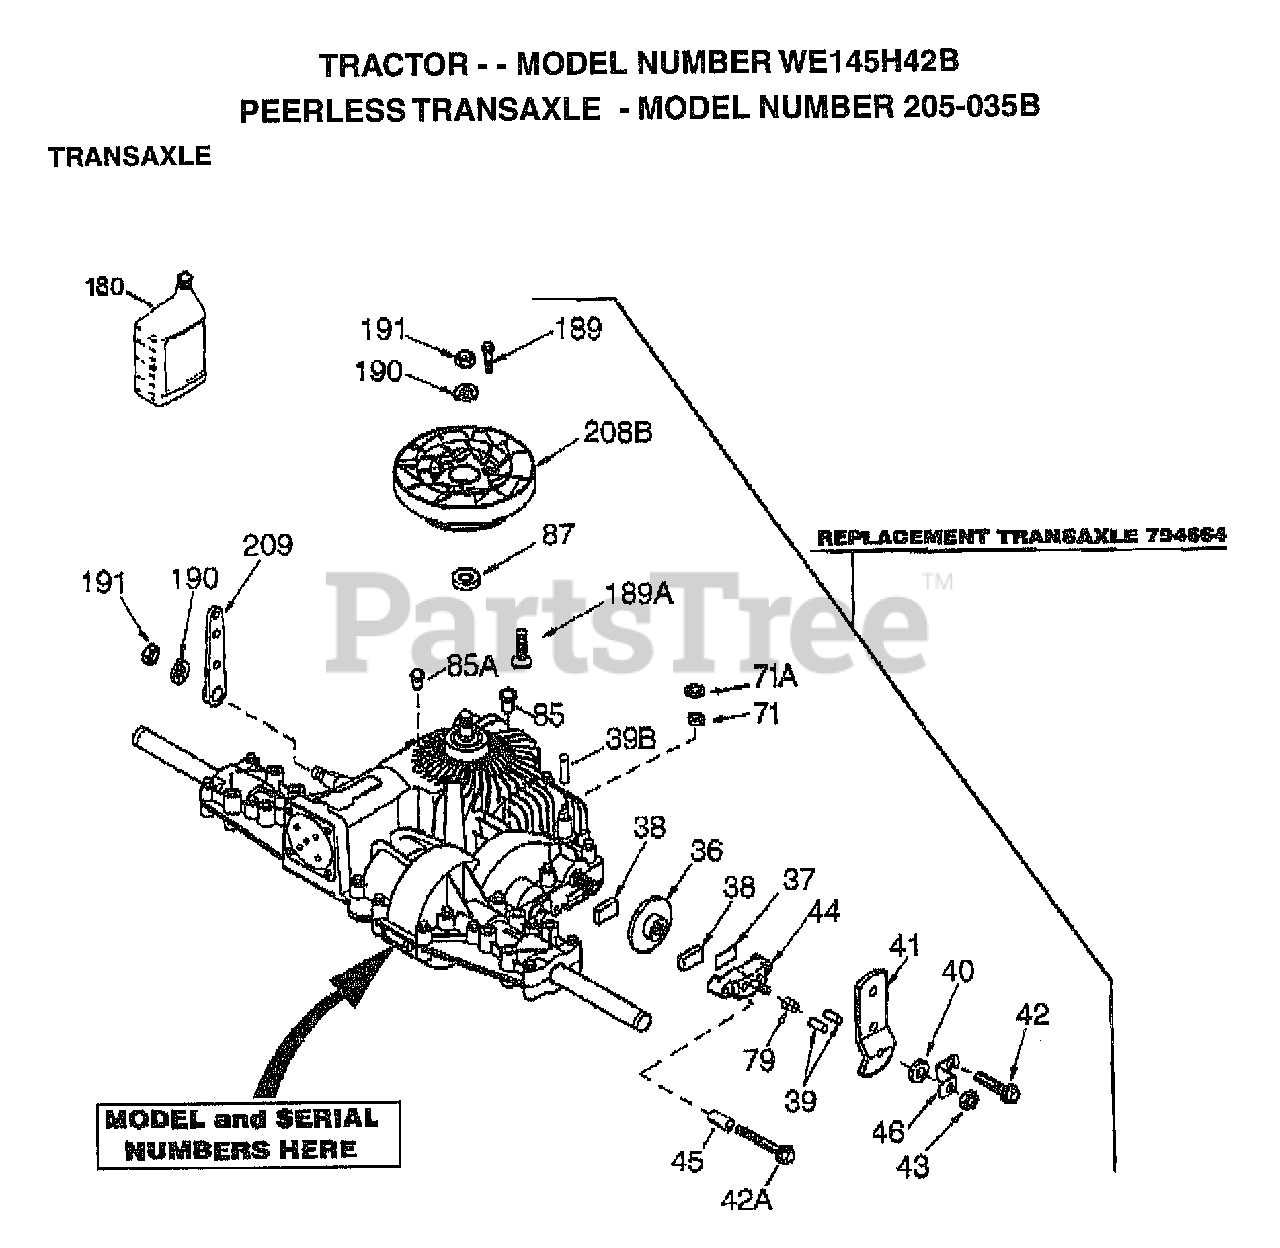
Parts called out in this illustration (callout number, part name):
37	PLATE BRAKE PAD
41B	BRAKE LEVER
42	SCREW, 1/4-20 X 1-1/4
42A	SCREW, 1/4-20 X 2-1/4
43	LOCKNUT 5/16-24
44	HOLDER BRAKE PAD
46	BRAKE LEVER BRACKET
71	SEAL SQUARE CUT
85	OIL FILL PLUG
85A	TUBE PLUG, 3/8"
180	GEAR OIL 80W90
189	DRIVE SCREW
208B	FAN/COUPLING
209	CONTROL LEVER
